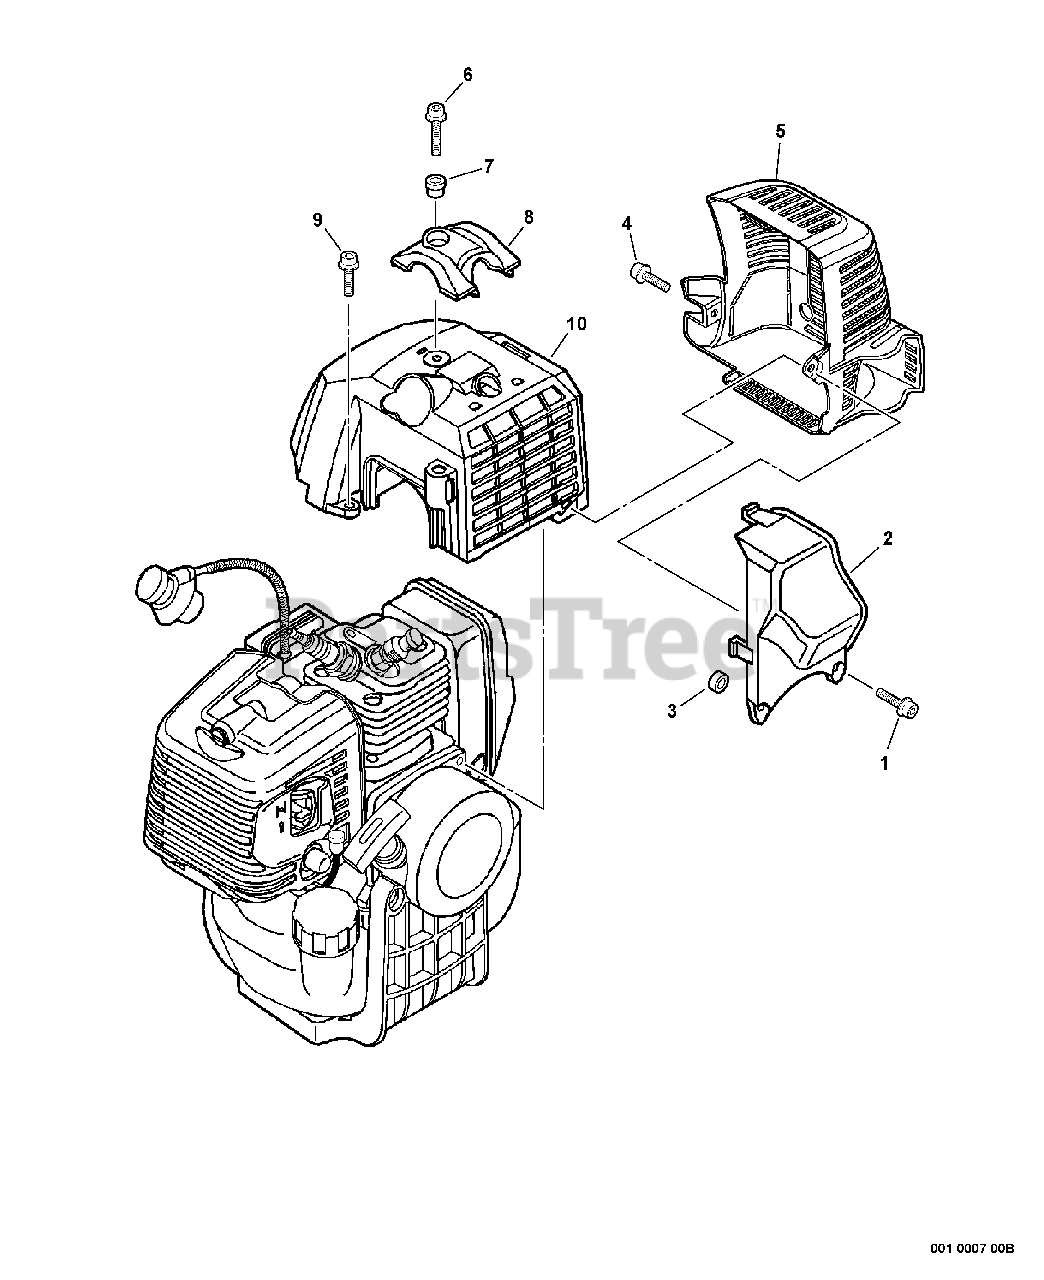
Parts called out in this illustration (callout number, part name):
1	BOLT 5×25
2	DEFLECTOR, HEAT
4	BOLT 5×12
5	COVER, MUFFLER
6	BOLT 5×20
7	COLLAR 5
8	GUARD, TOP
9	BOLT 5×12
10	COVER, ENGINE
